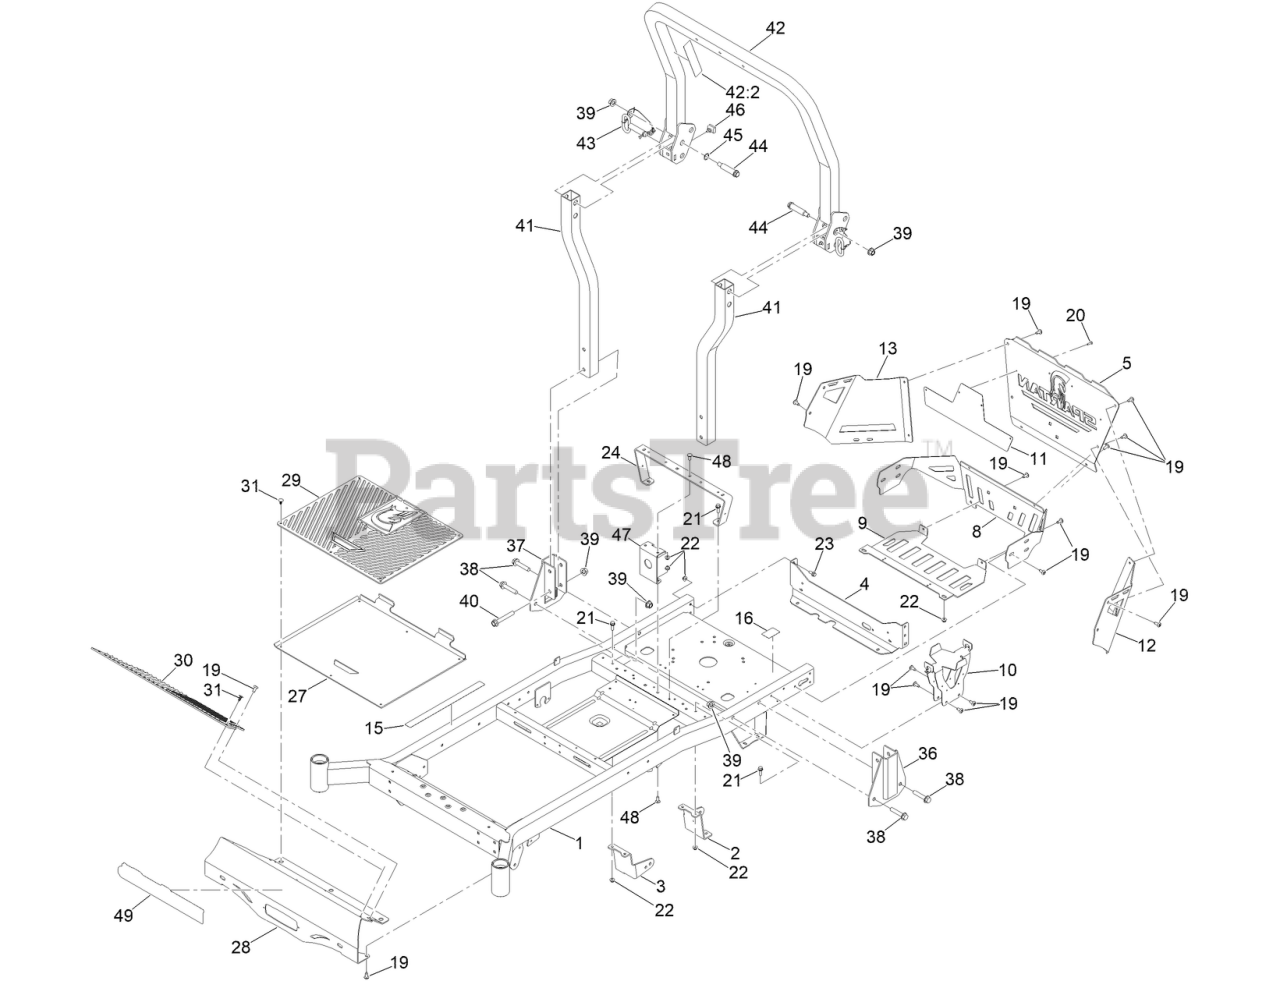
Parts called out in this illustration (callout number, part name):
1	SERVICE ASM-FRAME
2	MOUNT-DRIVE, LH
3	MOUNT-DRIVE, RH
4	PLATE-MOUNT, REAR
5	DEFENDER GUARD ENGINE [GRAY]
8	GUARD-MUFFLER, TOP
9	GUARD-MUFFLER, BOTTOM
10	TRAY-BATTERY
11	PLATE-BACK
12	COWLING-REAR, LH
13	COWLING-REAR, RH
15	DECAL-WARNING
16	DECAL-BYPASS
20	RIVET-TRIFOLD
21	SCREW-HHF
22	NUT-HF
23	SCREW-HHF
24	SUPPORT-SEAT
27	PAN-FLOOR [GRAY]
28	PLATE-FRONT
29	FLOOR MAT
30	FLOORMAT
31	PLUG-PLASTIC
36	BRACKET ROPS LH [BLK-TXT]
37	BRACKET ROPS RH [BLK-TXT]
38	SCREW-HHF
39	NUT-HF
40	SCREW-HHF
41	TUBE-ROPS, LOWER
42	TUBE-ROPS UPPER ASM
42:2	DECAL-WARNING
43	PIN-ROPS, ASM
44	BOLT-SHOULDER
45	WASHER-WAVE
46	BUMPER-ROPS
47	BRACKET-LATCH, FRAME (MTY/BTV)
48	SCREW-CARR
49	DECAL-BUSHRANGER
